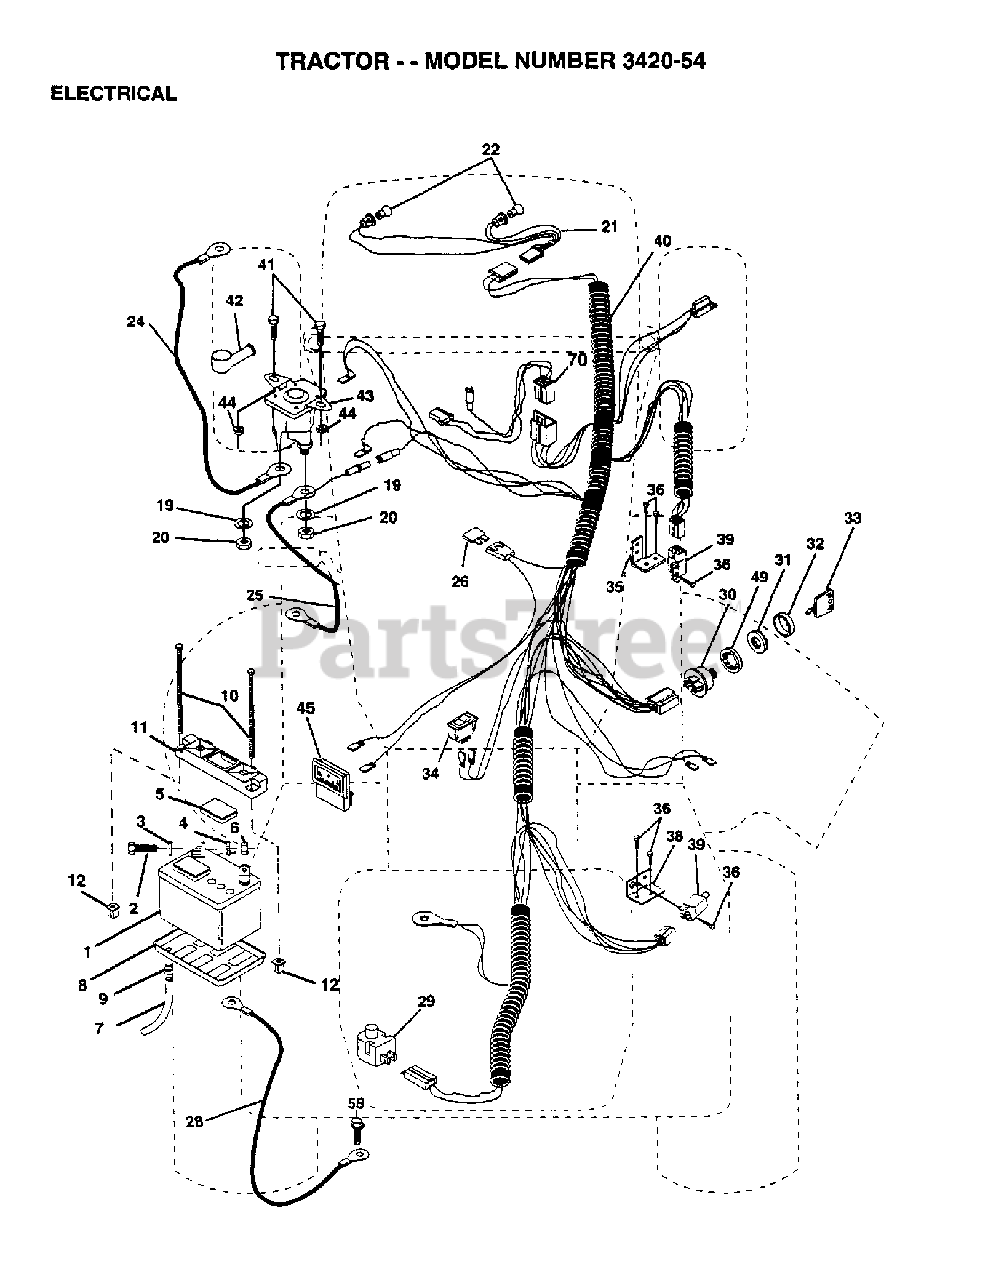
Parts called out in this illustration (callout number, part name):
1	BATTERY
2	BOLT.HEX.1/4.X.3/4.DICHROMATE
3	WASHER
4	LOCKWASHER
5	CAP BATTERY NLA
6	NUT
7	BATT DRAIN TUBE T
8	TRAY.BATTERY
9	HOSE CLAMP T
10	BOLT 1/4-20 X 7.5
12	Poulan TBD
20	NUT
22	LIGHTBULB
24	CABLE BATTERY 6 GA 22" W/16W
25	BATTERY CABLE
26	FUSE *
28	CABLE GROUND 6 GA 21" 90T BLK
29	SWITCH SEAT
30	Ignition Switch Kit
31	NUT, IGNITION
32	COVER KEY IGNITIO
33	KEY MLD GEN DELTA
34	SWITCH LT
35	BRACKET LT
39	SWITCH INTERLOCKT
42	TERMINAL COVER
43	Solenoid Kit, .95
44	LOCKNUT.NYLOC.1/4-20
45	AMMETER
55	SCREW LT
70	HARNESS, ENGINE
